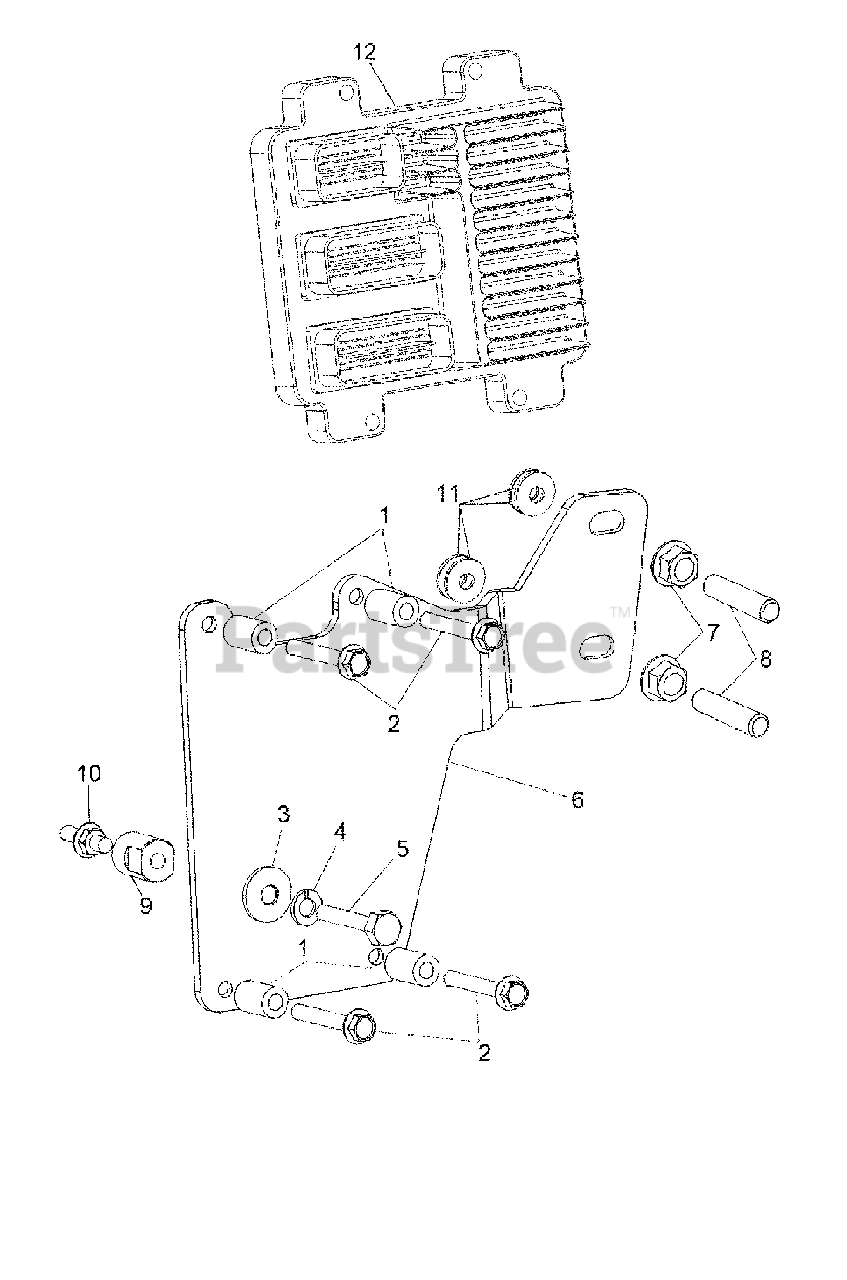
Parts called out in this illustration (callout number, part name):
1	SPACER
2	SCREW
3	WASHER
4	WASHER-LOCK
5	BOLT
6	BRACKET
7	NUT
8	STUD
9	SPACER
10	STUD
11	WASHERS
